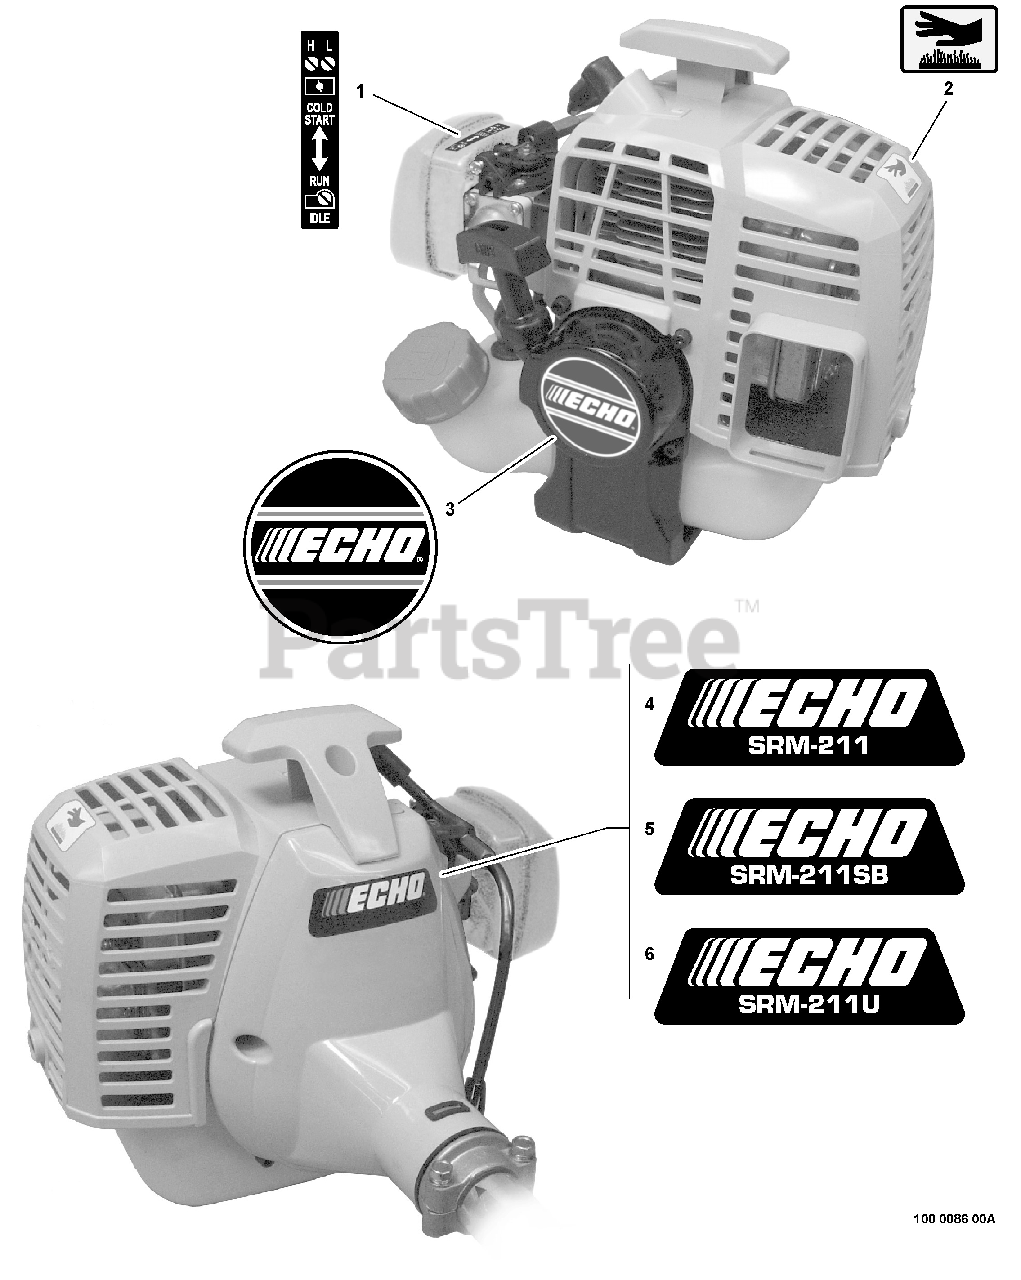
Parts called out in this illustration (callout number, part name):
1	LABEL - CHOKE
2	LABEL - HOT SURFACE
3	LABEL - ECHO
4	LABEL - MODEL SRM-211i
5	LABEL - MODEL SRM-211SB
6	LABEL - MODEL SRM-211U
